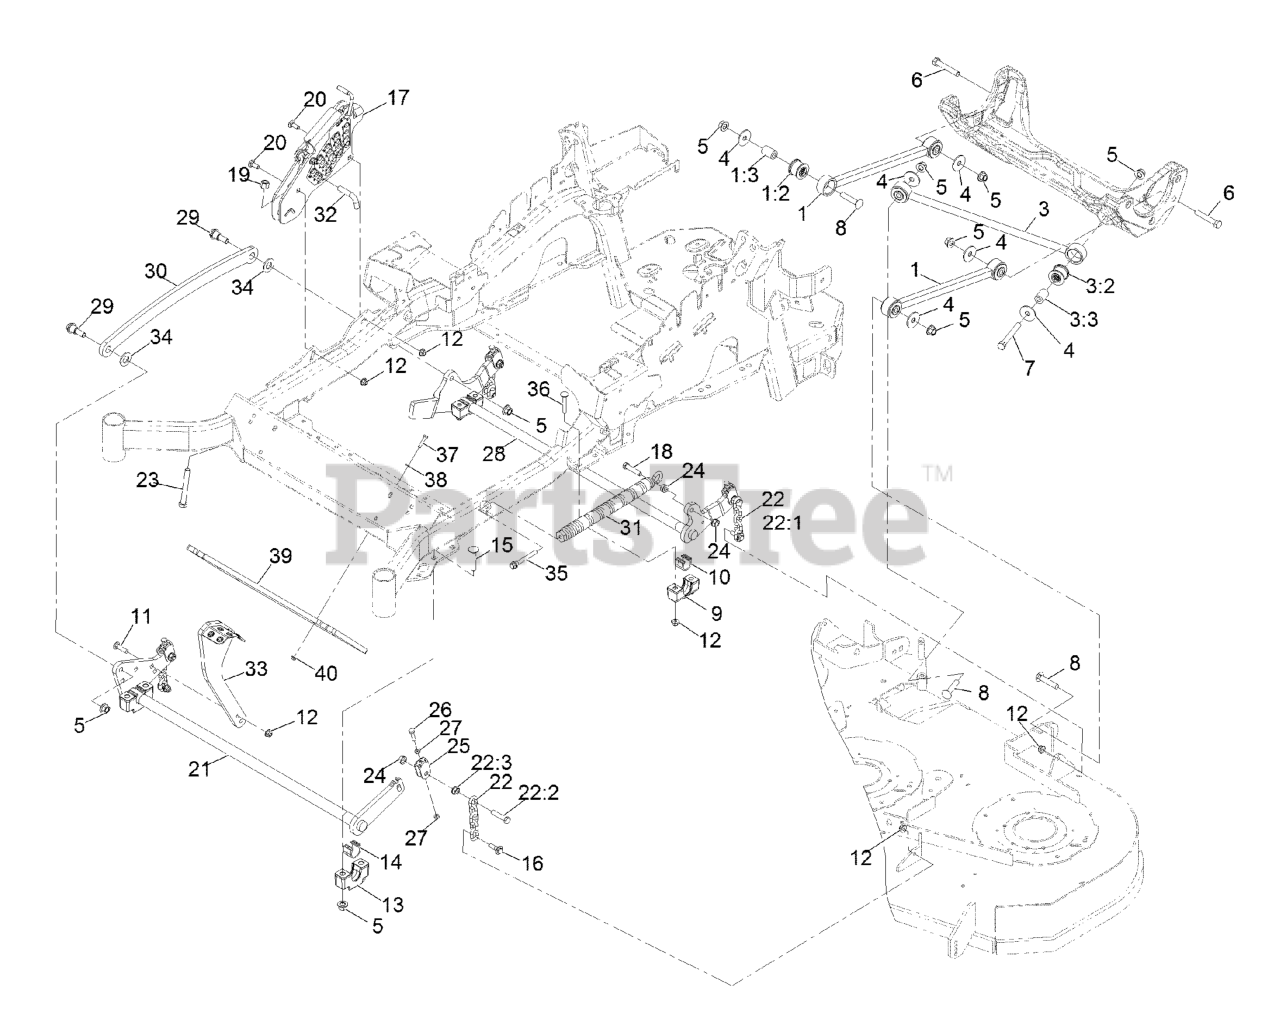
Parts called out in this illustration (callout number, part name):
1	LONG STRUT ASM
1:2	BUSHING-SUSPENSION, RUBBER
2	PANHARD ROD ASM
2:2	BUSHING-SUSPENSION, RUBBER
3	WASHER-THRUST
4	Nut-Lock 1/2-13
5	SCREW-HH
6	SCREW-HH
7	SCREW-CARR
8	SUPPORT-CROSS SHAFT, BEARING REAR
9	BEARING-CROSS SHAFT, REAR
10	SCREW-CARR
11	NUT-HF, NI
12	SUPPORT-CROSS SHAFT, BEARING
13	BEARING-CROSS SHAFT, FRON
14	Bolt-Carriage 1/2-13 X 2 1/2 Spl Neck
15	SCREW-SHOULDER, HHF
16	HOC ASM
17	SCREW-HH
18	NUT-LOCK, NI
19	BOLT-CARR
20	DECKLIFT-FRONT
21	DECK LIFT CHAIN ASM
21:1	CHAIN-LIFT, DECK
21:2	SCREW-HH
22	BOLT-TAP
24	YOKE-ADJUST, DECK
25	SCREW-HH
26	NUT-JAM
27	LIFT-DECK, REAR
28	SCREW-SHOULDER, HHF 1/2-13 X 1.12
29	LINK-LIFT, DECK
30	SPRING-EXTENSION
31	PIN-HOC
32	LEVER-FOOT
33	WASHER-FLAT
34	BOLT-SHOULDER
39	Bolt-Carriage 3/8-16 X 2 1/4
